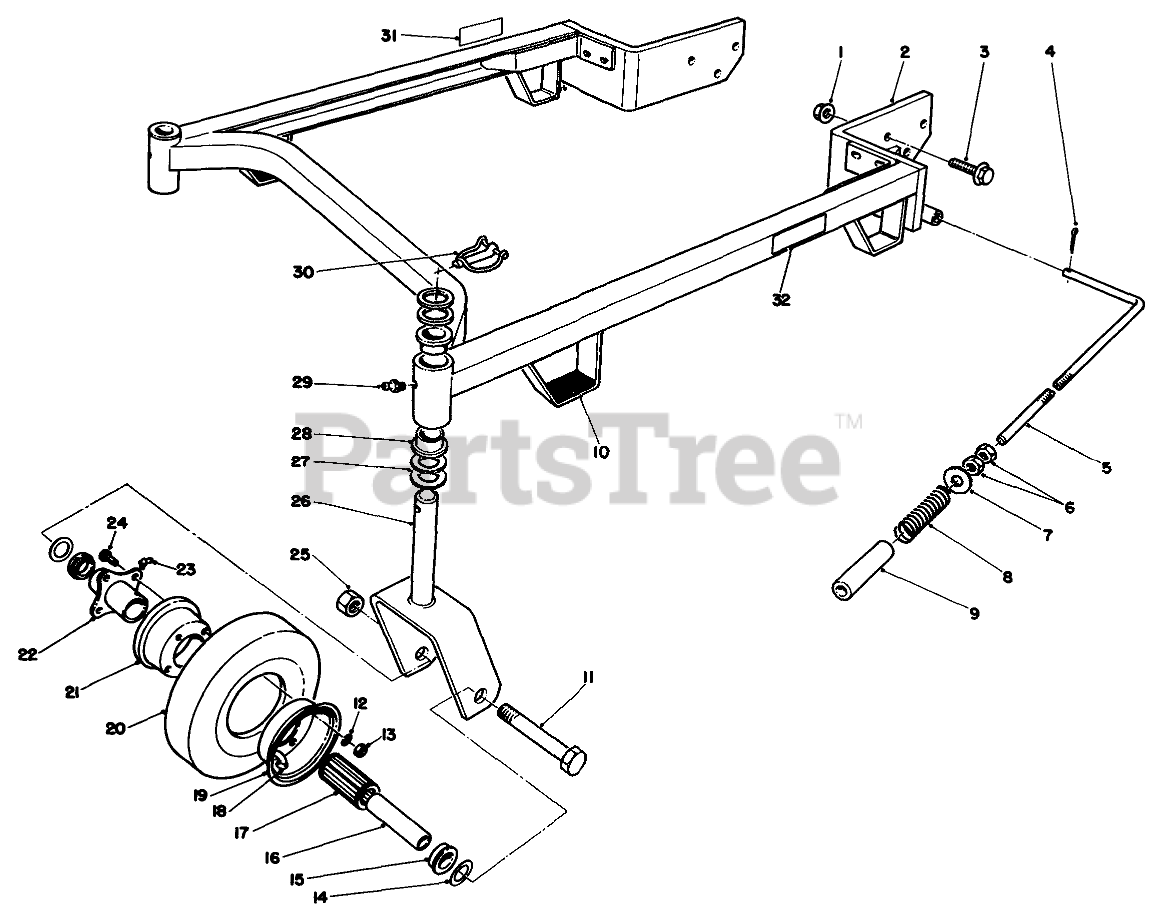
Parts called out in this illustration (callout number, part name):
1	NUT-HF
2	Suspension Frame (Incl. Ref. #28)
3	SCREW-HHF
4	PIN-COTTER
5	ADJUSTING SHAFT
6	NUT-JAM
7	WASHER
8	COMP. SPRING
9	SLEEVE-TUBE, 36 INCH
10	Pad-Rubber
11	SCREW-HH
12	WASHER-LOCK
13	NUT-HEX
14	SPACER-WHEEL
15	RETAINER
16	Bushing-Spanner
17	BEARING-ROLLER
19	WHEEL HALF-MALE
20	TIRE-8 Inch (4-PLY)
21	WHEEL HALF-FEMALE
22	HUB-CENTERED
23	FITTING-GREASE
24	WHEEL BOLT
25	NUT-LOCK
26	FORK-Castor
27	WASHER-THRUST
28	Bushing
29	FITTING-GREASE
30	PIN-LYNCH
31	DECAL-CAUTION, DEFLECTOR
32	DECAL-HOC, LH
